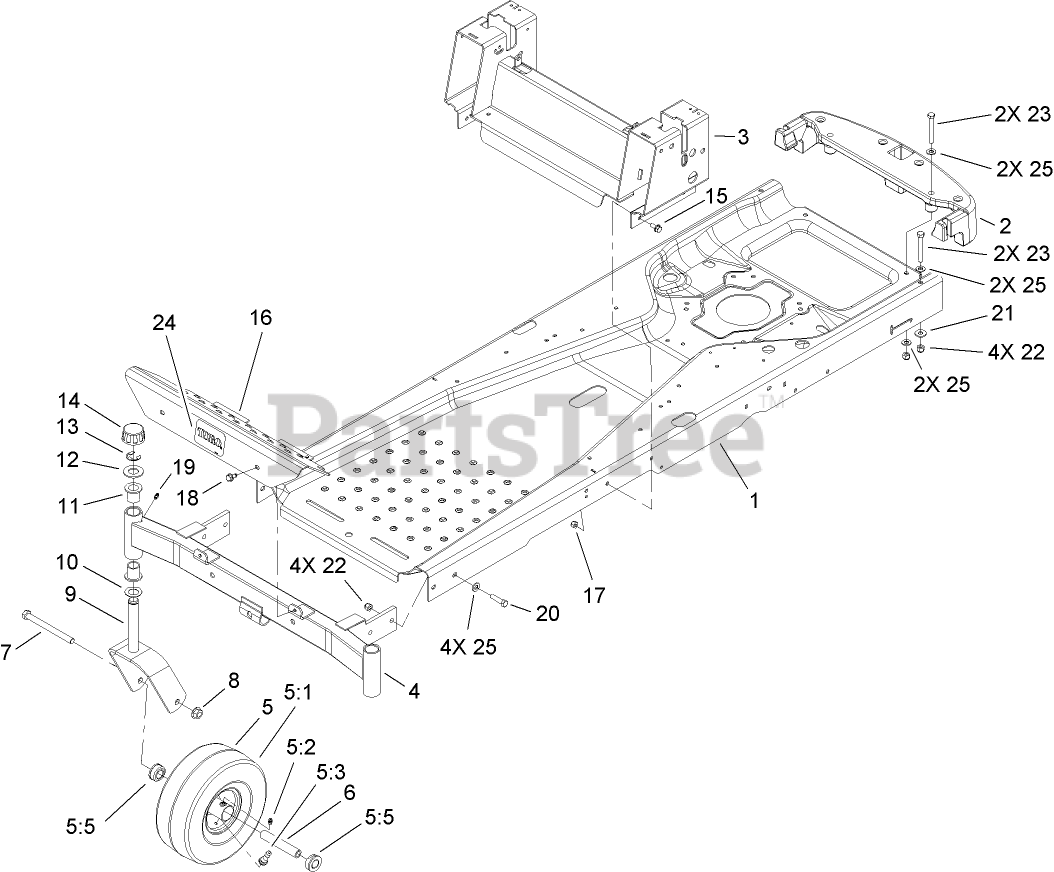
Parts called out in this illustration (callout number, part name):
2	BUMPER-REAR
4	FRONT AXLE ASM
5	FRONT WHEEL AND TIRE ASM
5:2	FITTING-GREASE
5:5	BUSHING-FLANGE
6	BUSHING-SPANNER
7	SCREW-HH
8	NUT-HF
9	CASTER FORK ASM
10	WASHER-THRUST
11	BEARING-FLANGED
12	WASHER
13	RING-RETAINING, EXT
14	CAP-HUB
15	SCREW-HHF
16	FOOTREST
17	NUT-LOCK, NI
18	SCREW-HWH
19	FITTING-GREASE
20	SCREW-HH
21	WASHER-HARDENED
22	NUT-LOCK, NI
23	SCREW-HH
24	DECAL
25	WASHER-FLAT
